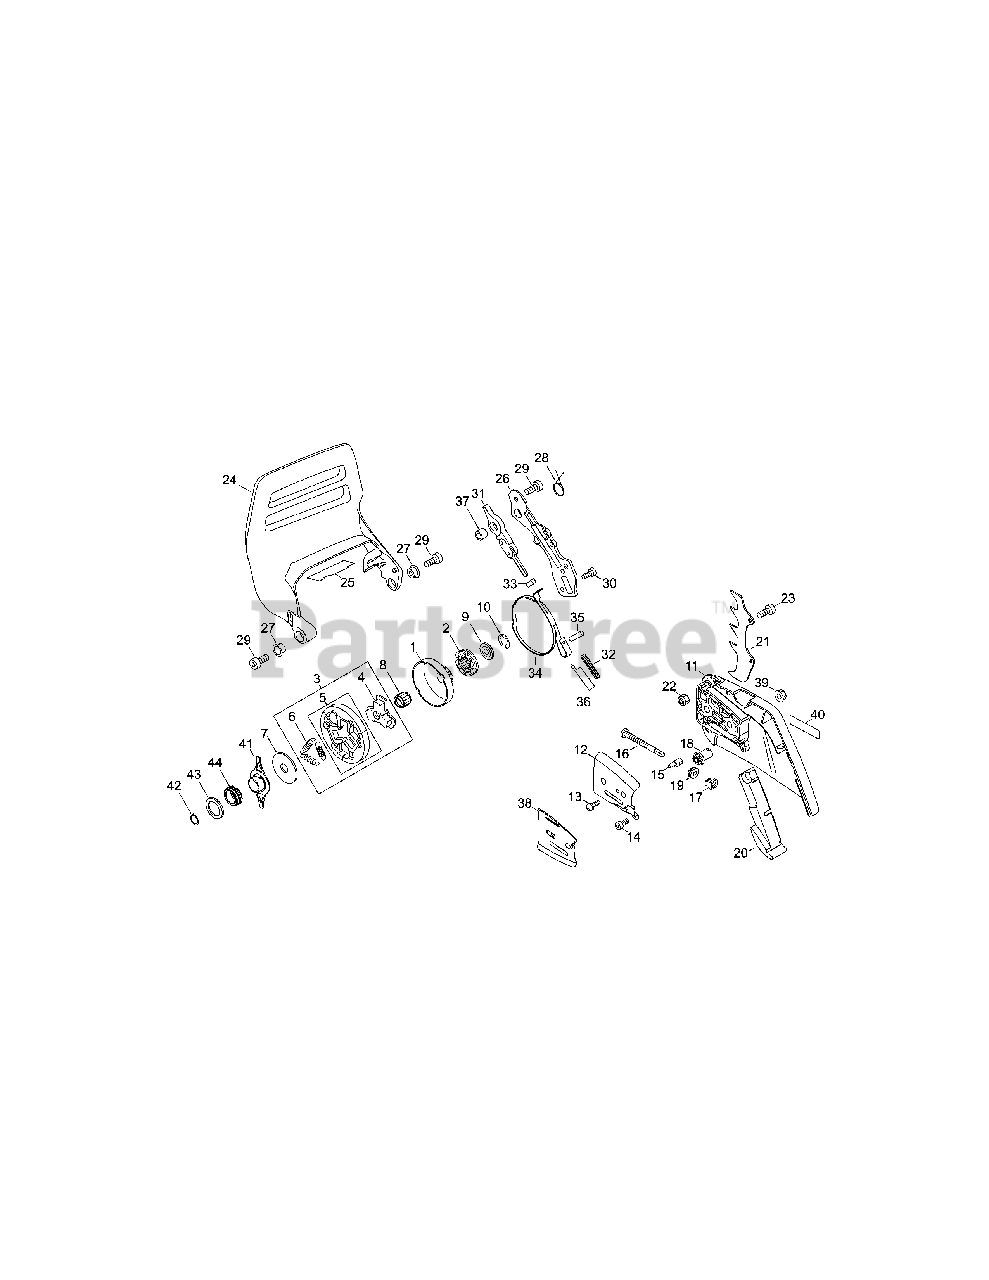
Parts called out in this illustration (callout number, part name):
1	DRUM, CLUTCH
2	SPROCKET, RIM 68210S
3	CLUTCH ASY
4	HUB, CLUTCH
5	CLUTCH SHOE SET
6	SPRING,TENSION
7	PLATE, CLUTCH
8	BEARING,NEEDLE 10
9	WASHER,CIRCULAR 10
11	GUARD, SPROCKET
12	PLATE,SPROCKET GUARD
14	BOLT, TORX 4
15	TENSIONER, CHAIN
17	COLLAR,8
18	GEAR,BEVEL
19	GEAR,BEVEL
20	PAD, GUARD
22	NUT, LOCK 5
23	BOLT, TORX 5
24	LEVER, BRAKE
25	WASHER,SQUARE
26	COVER,BRAKE
27	COLLAR,10
28	SPRING,TORSION
29	BOLT, TORX 5
30	BOLT, TORX 4
31	CONNECTOR, BRAKE
32	SPRING,COMPRESSION
34	BAND, BRAKE
36	PLATE, SIDE
37	COLLAR,10
38	PLATE,SPROCKET GUARD
40	LABEL,ECHO
41	COLLAR,14
42	CIRCLIP 15
43	WASHER,CIRCULAR 16-1
44	GEAR,WORM
